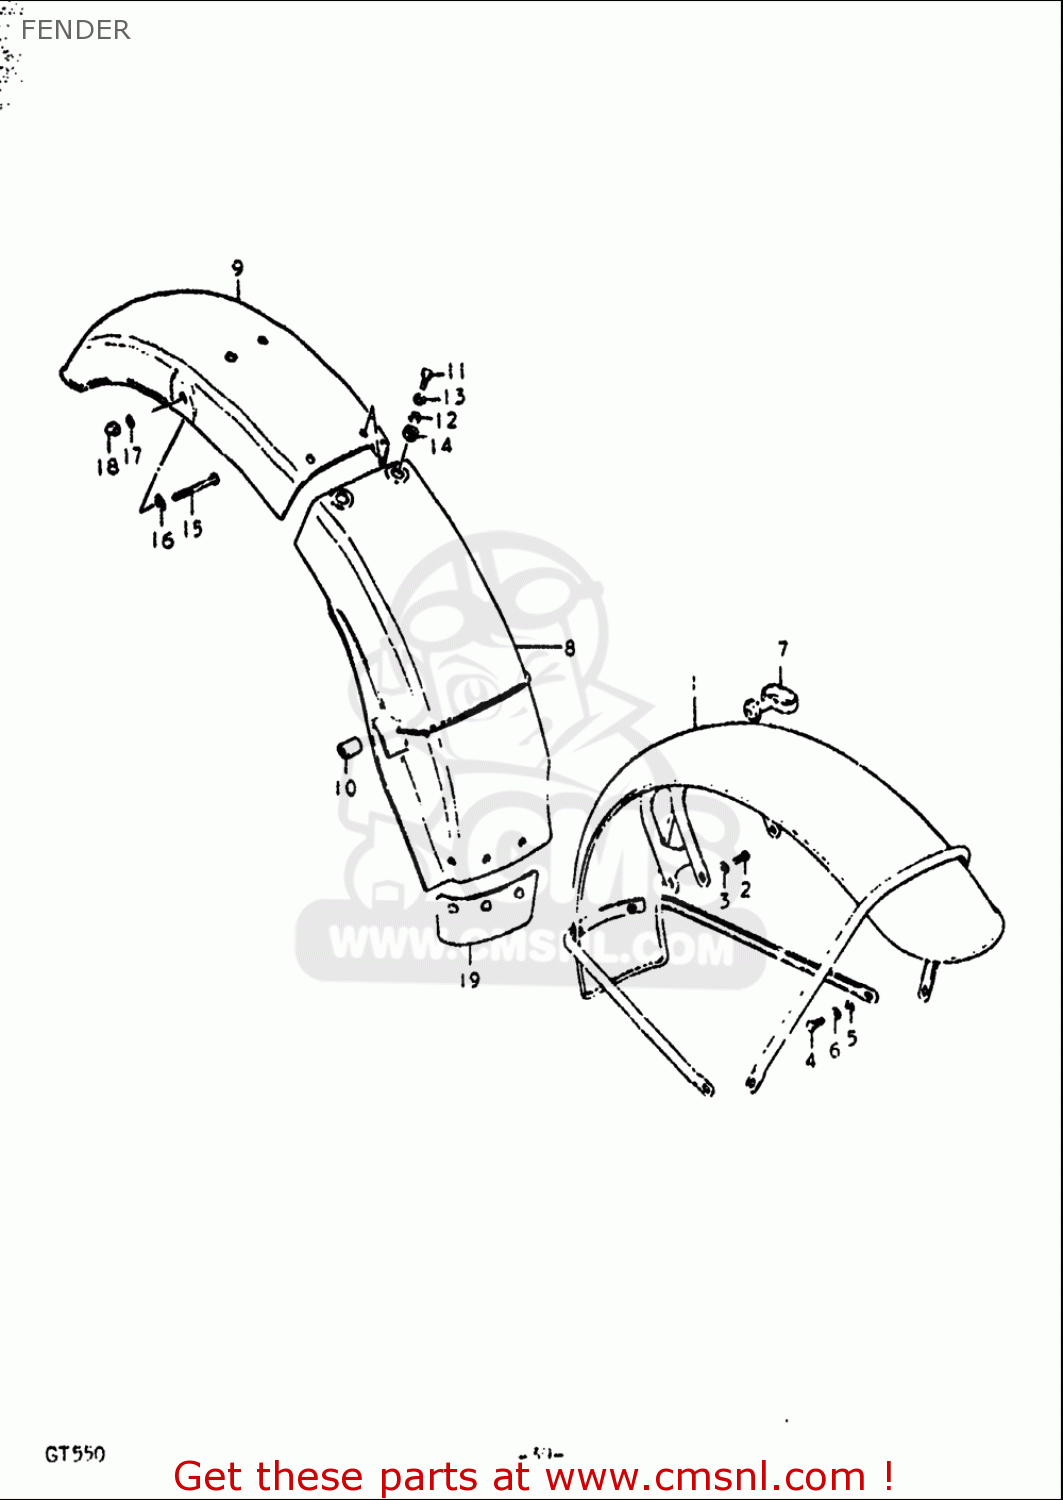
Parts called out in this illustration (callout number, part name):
2	BOLT
3	WASHER,LOCK
4	BOLT
5	WASHER
6	WASHER,LOCK
7	GUIDE,CABLE
8	BODY,RR FENDER FR
10	CUSHION
11	BOLT
12	WASHER
13	WASHER,LOCK
14	SPACER (6.5X20X5)
15	BOLT
16	WASHER
17	WASHER,LOCK
18	NUT
19	GUIDE,RR FENDER MUD
